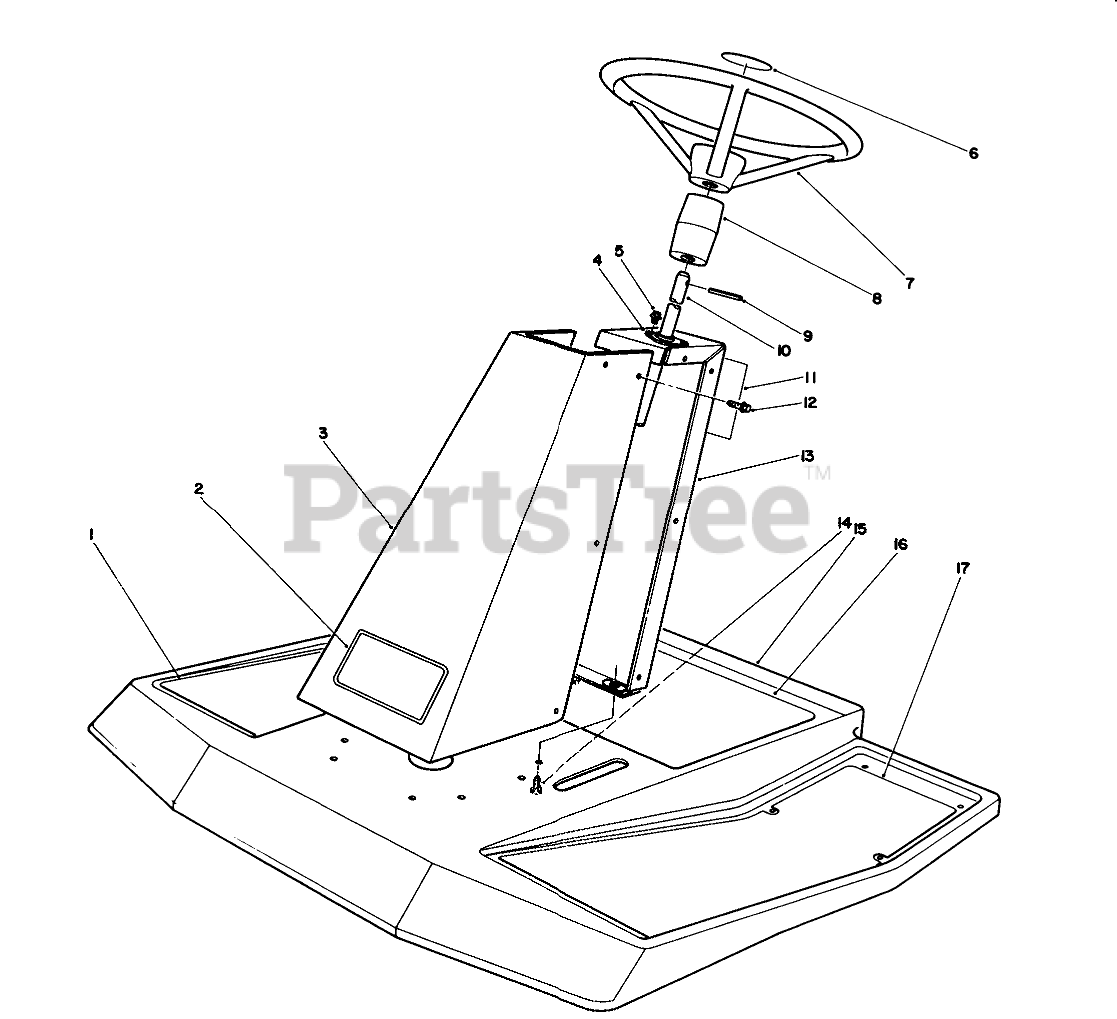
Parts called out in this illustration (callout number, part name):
1	RH FOOT TREAD
2	DECAL
3	STEERING TOWER WA R
4	GUIDE-STRG SHAFT
5	SCREW-HWHTF
6	STEERING WHEEL CAP
7	STEERING WHEEL
8	STRG. SHAFT COVER
9	PIN-ROLL
10	STEERING SHAFT WA
11	DECAL - WARNING
12	Screw-Ind. Hd.
13	Panel-Steering Tower (Incl. Ref. #11)
14	SCREW-HH
15	Pan-Floor (Incl. Ref. #1, 16, & 17)
16	DECAL - OPERATION
17	LH FOOT TREAD
